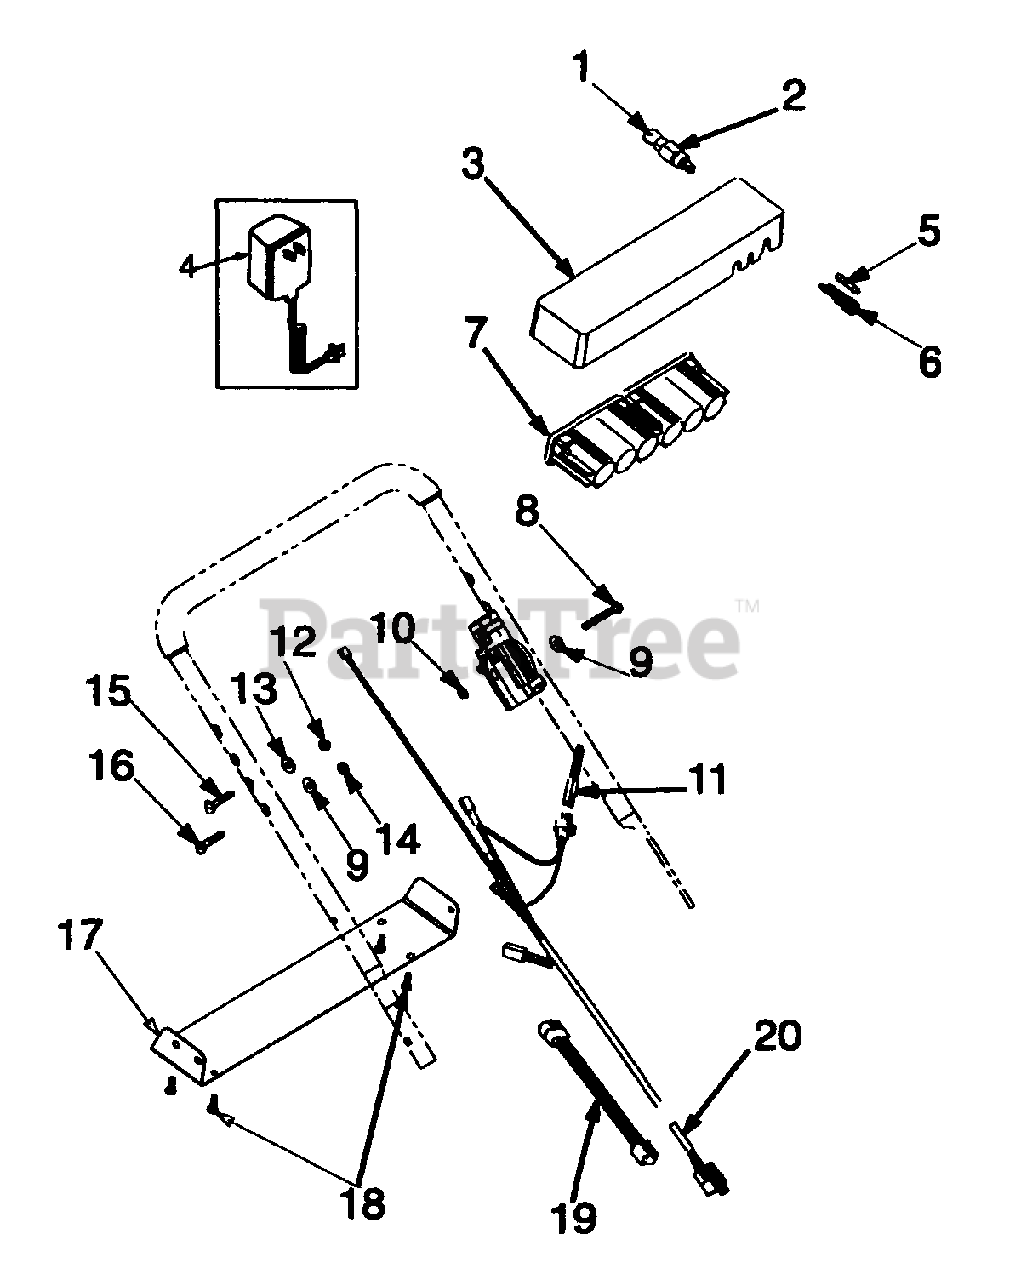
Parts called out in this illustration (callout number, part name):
1	Ignition Key
2	Key Switch
3	Battery Tray
4	Battery Charger
5	Fuse 7.5 Amp
6	Fuse Holder
7	Battery 12V
8	Hex Screw:1/4-20:2.0
9	Bell Washer .265 x .75 x .062
10	Special Hex Nut 5/16-18
11	Plug
12	Nut 5/16-18
13	Bell Wash .340 ID x .872 OD
14	Hex Nut 1/4-20
15	Carriage Bolt 5/16-18 x 1
16	Carriage Screw
19	Harness Extension
20	Harness
